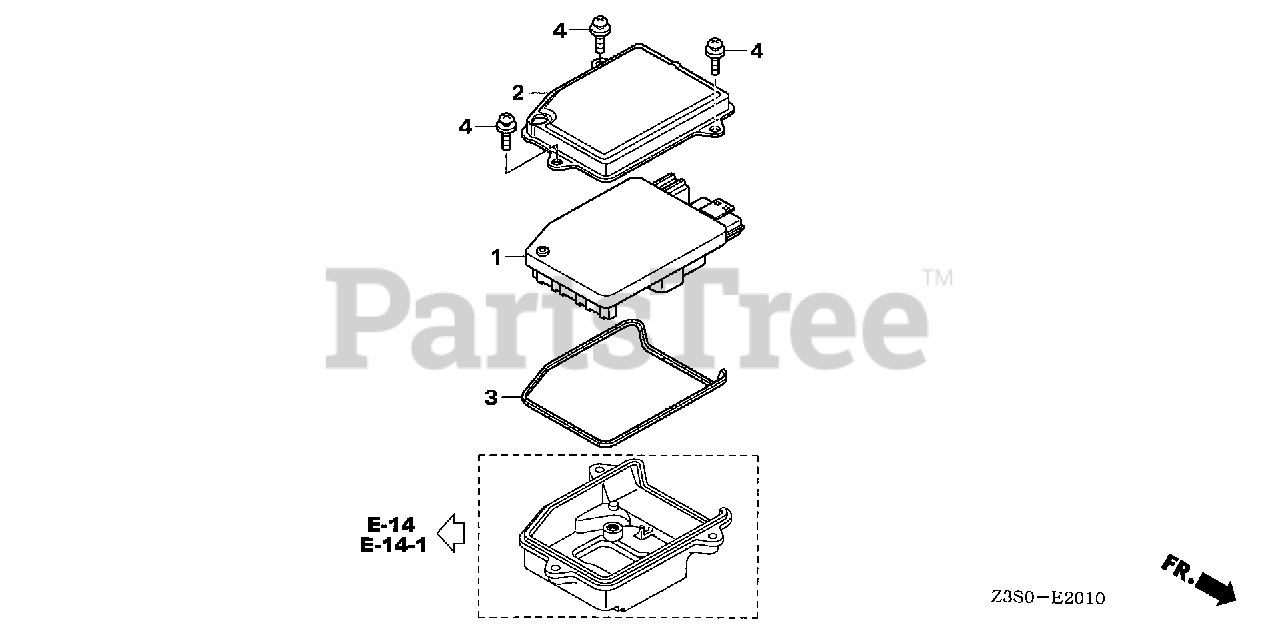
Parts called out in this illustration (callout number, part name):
1	CONTROL UNIT, ELECTRONIC
2	COVER, ELECTRONIC CONTROL UNIT
3	GROMMET, ELECTRONIC CONTROL UNIT COVER
4	SCREW-WASHER (4X10)
